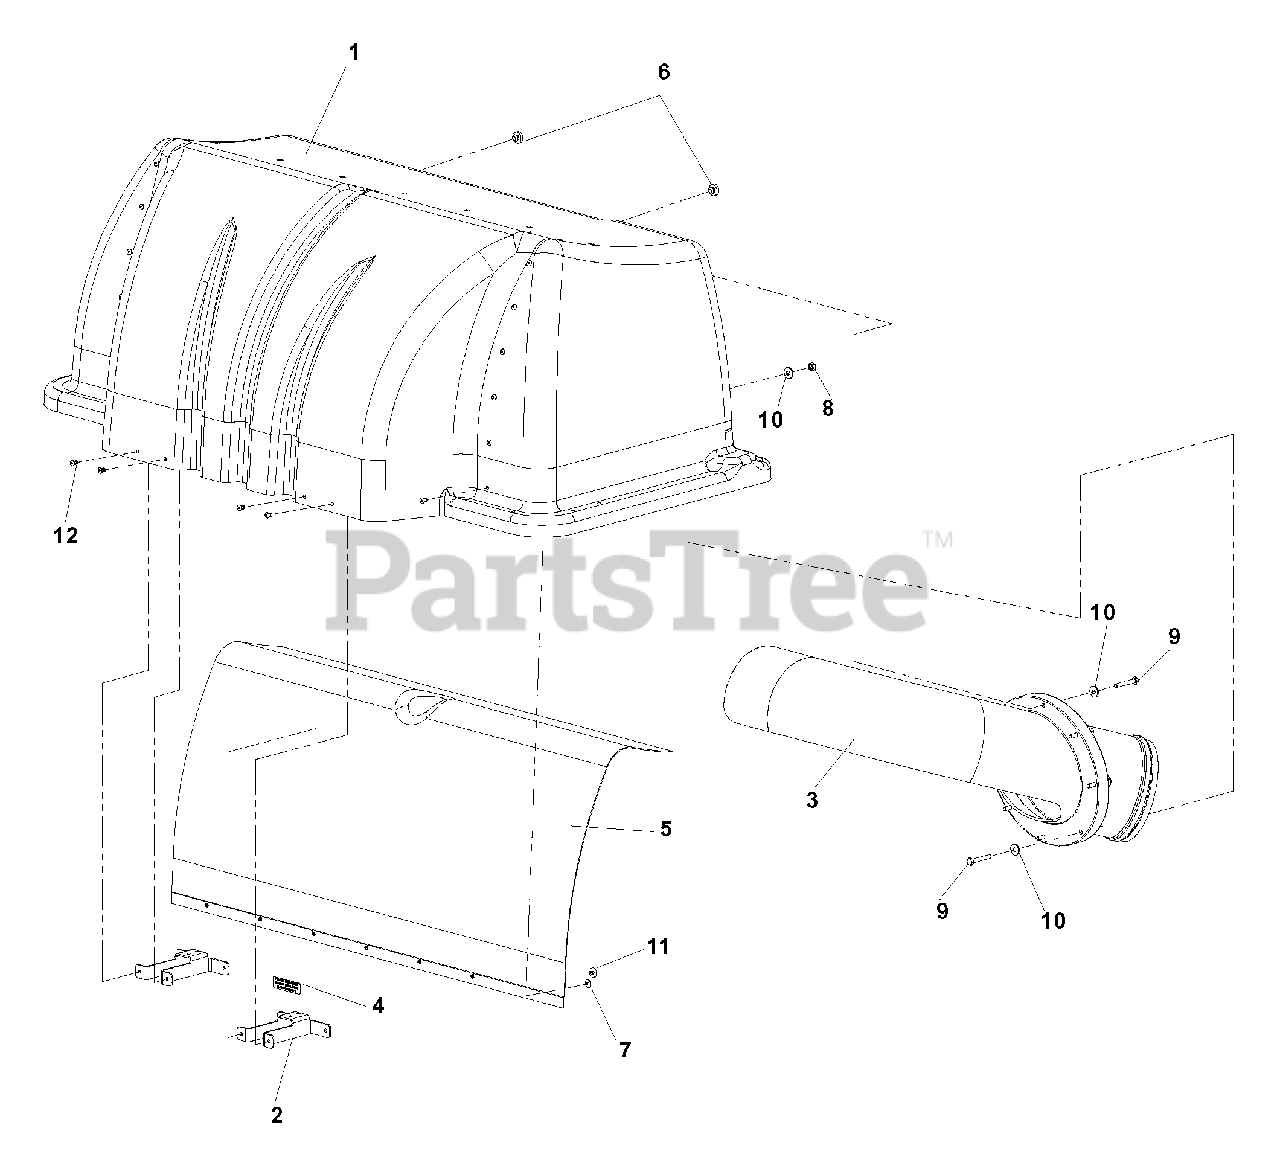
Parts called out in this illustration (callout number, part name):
2	SUPPORT, DRAW LATCH
3	INLET TUBE
4	DECAL, VENTILATION
5	MESH, POLY DIAMOND
6	GROMMET, BUMPER
7	WASHER, #10
8	NUT, 1/4 -20, NYLOC
9	HCS, 1/4 -20 x 1 3/4,
10	WASHER, 1/4
11	RIVET, 3/16 x 1/4
12	RIVET, 3/16 , STAVEX
